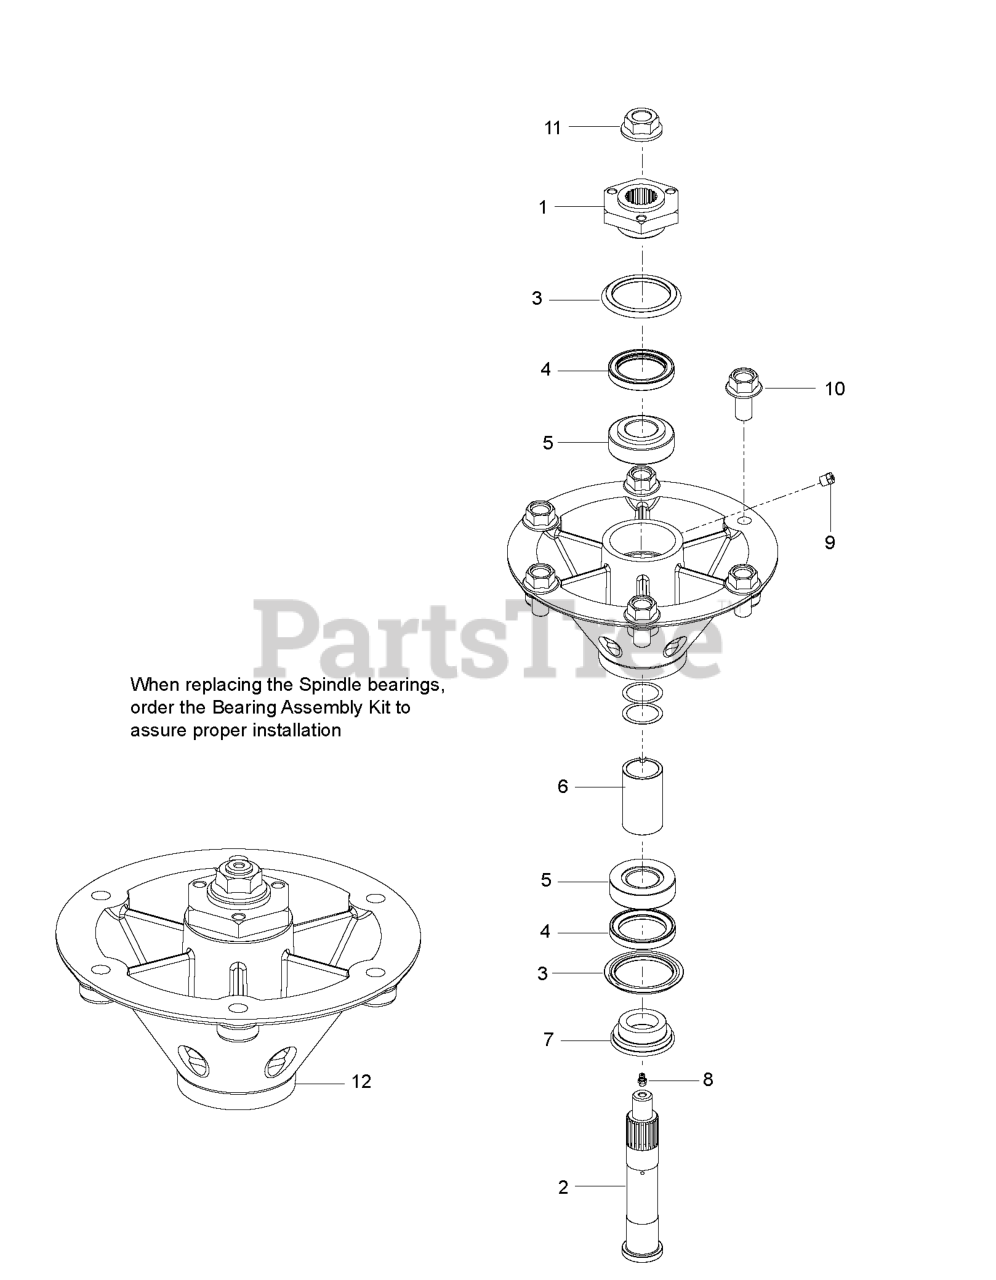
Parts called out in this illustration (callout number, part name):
3	SEAL V-RING 55MM
4	SEAL SHAFT
5	BEARING
8	ZERK
9	PLUG-VENTED
10	HHFS 1/2-13 X 1 GR5 ZD
11	NUT FLANGE 3/4-16
12	RP_SPINDLE.ASM.10".IRON.1/8-27
